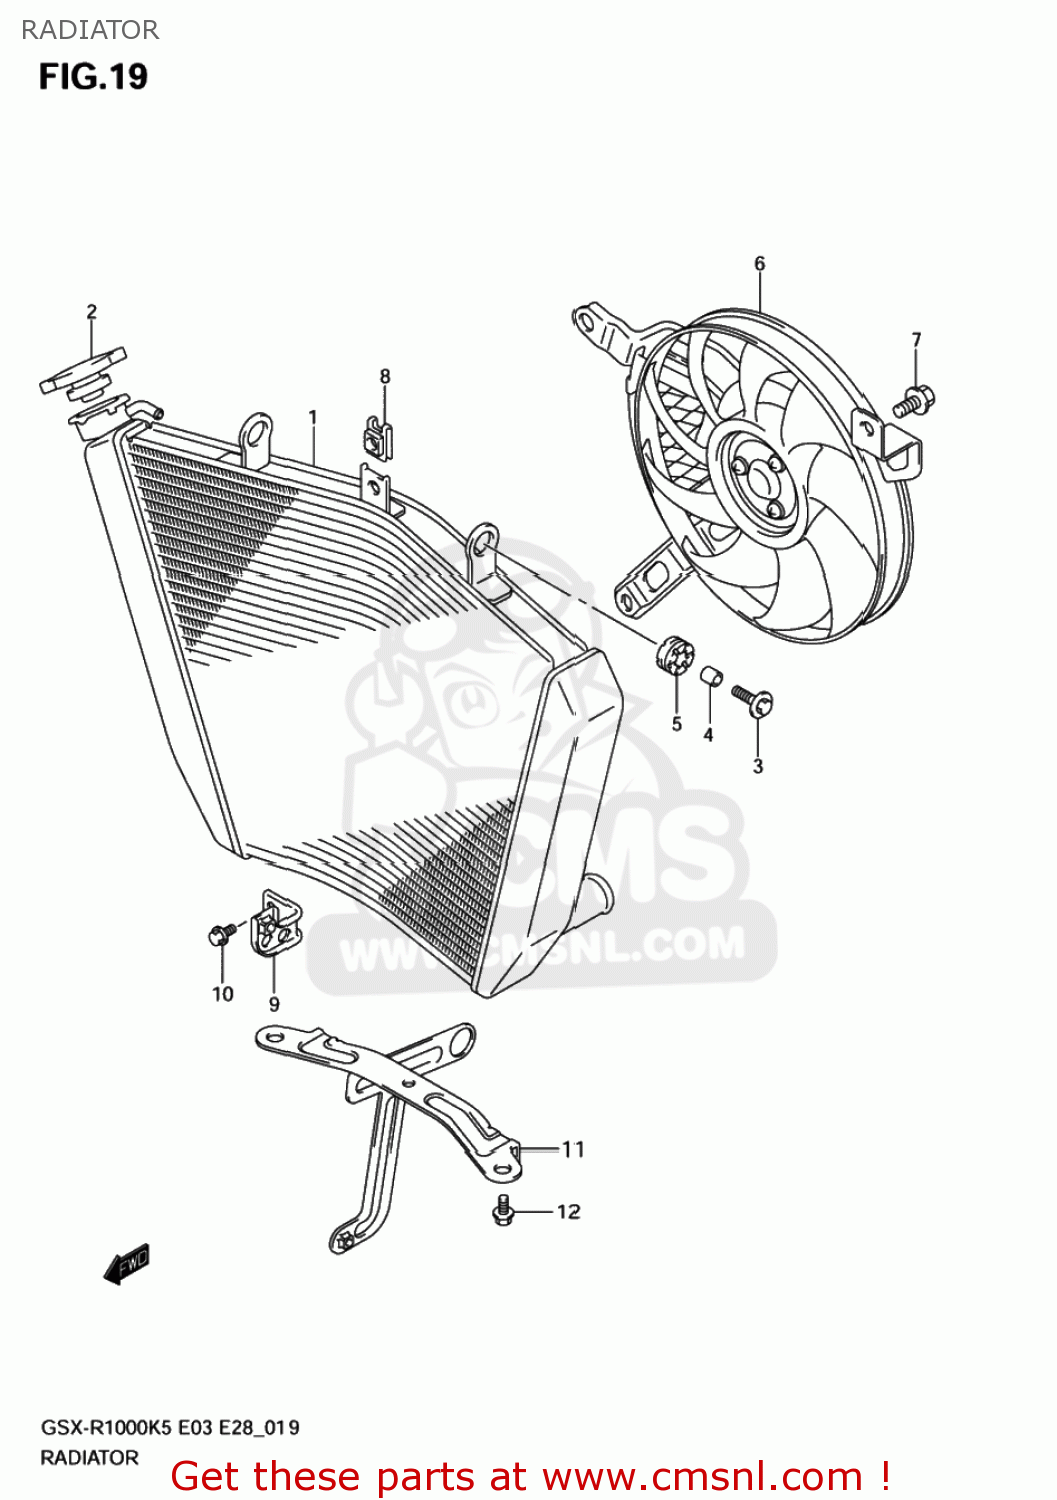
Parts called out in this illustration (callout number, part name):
1	RADIATOR ASSY,WATER
2	CAP COMP,RADIATOR
3	BOLT(6X25)
4	SPACER(6.5X10X12)
5	CUSHION
6	FAN ASSY,RADIATOR
7	BOLT,FAN ASSY
8	NUT,FAN ASSY
9	BRACKET,RDTR & OIL COOLER
10	BOLT
11	BRACKET,RADIATOR SUPPORT
12	BOLT
